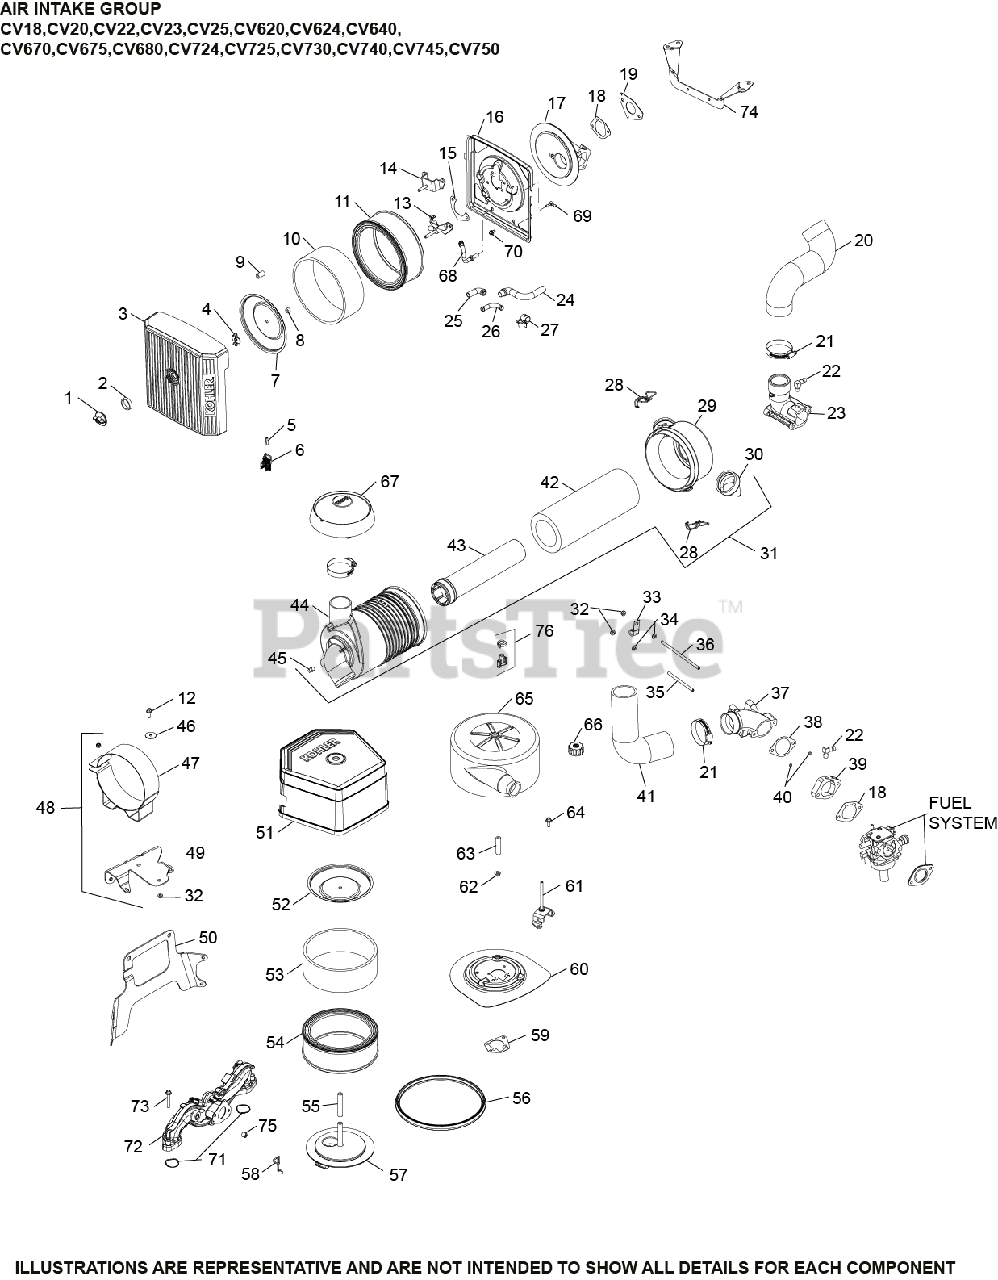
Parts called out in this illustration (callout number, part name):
12	SCREW, FLG M6X1.0X16
12	SCREW, THREAD FORMING
18	GASKET, AIR CLEANER BASE
21	CLAMP, HOSE
22	CONNECTOR, HOSE
23	ELBOW, AIR CLEANER
28	LATCH ASSEMBLY
29	COVER ASSEMBLY
30	VALVE, ACUATOR
31	AIR CLEANER (W/DIRTY-SIDE EVAP FITTING)
32	NUT, LOCK M6X1.0
35	STUD, M6X1.0X180
42	ELEMENT, AIR FILTER - PRIMARY
43	ELEMENT, AIR FILTER - SAFETY
44	HOUSING, HD AIR CLEANER
45	PLUG, PIPE
46	WASHER, FLAT 1/4"
47	BRACKET, AIR CLEANER
49	BRACKET, AIR CLEANER MOUNTING
50	BRACKET, MAIN SUPPORT
67	HOOD, INLET
76	KIT, ADAPTER TUBE
